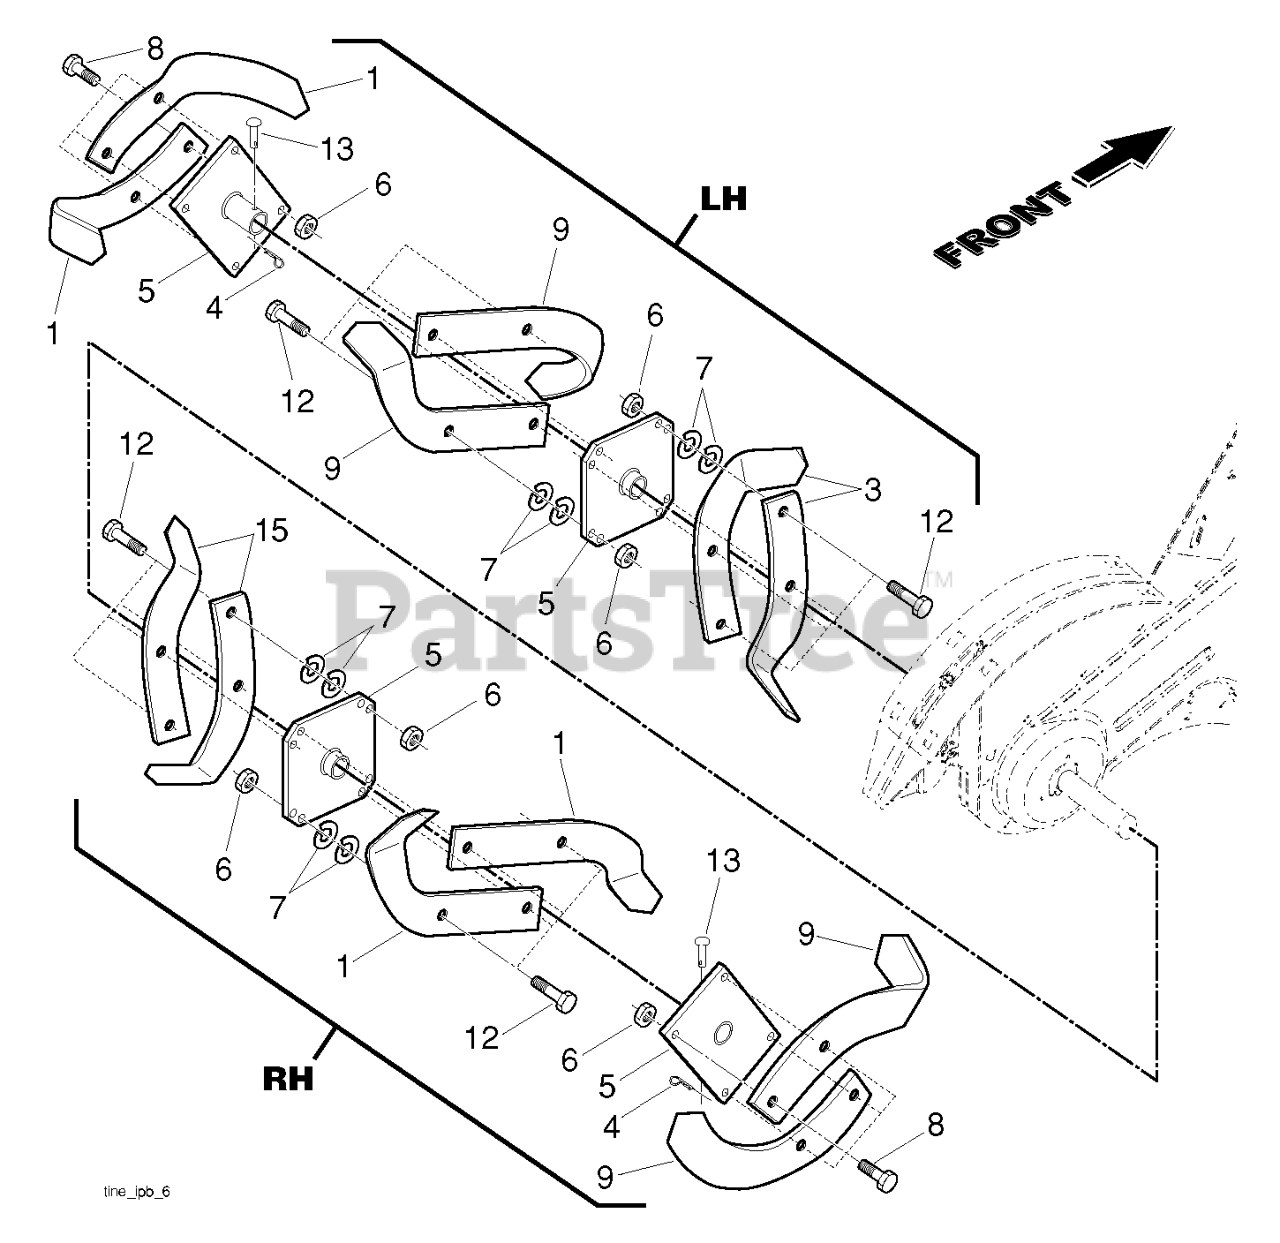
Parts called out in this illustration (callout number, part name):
1	TINE, LH 14"
3	TINE.LH.14".CRT
4	SPRING RETAINER
5	HUB ASSY
6	NUT CROWNLOCK 3/8-24
7	WASHER, LOCK 3/8
8	BOLT.HEX.001X20.37-24X1.ZINC
9	TINE, RH 14"
12	BOLT.3/8-24X1-1/2
13	RIVET.PAN.HD.DRILLED
15	TINE.RH.14".CRT
